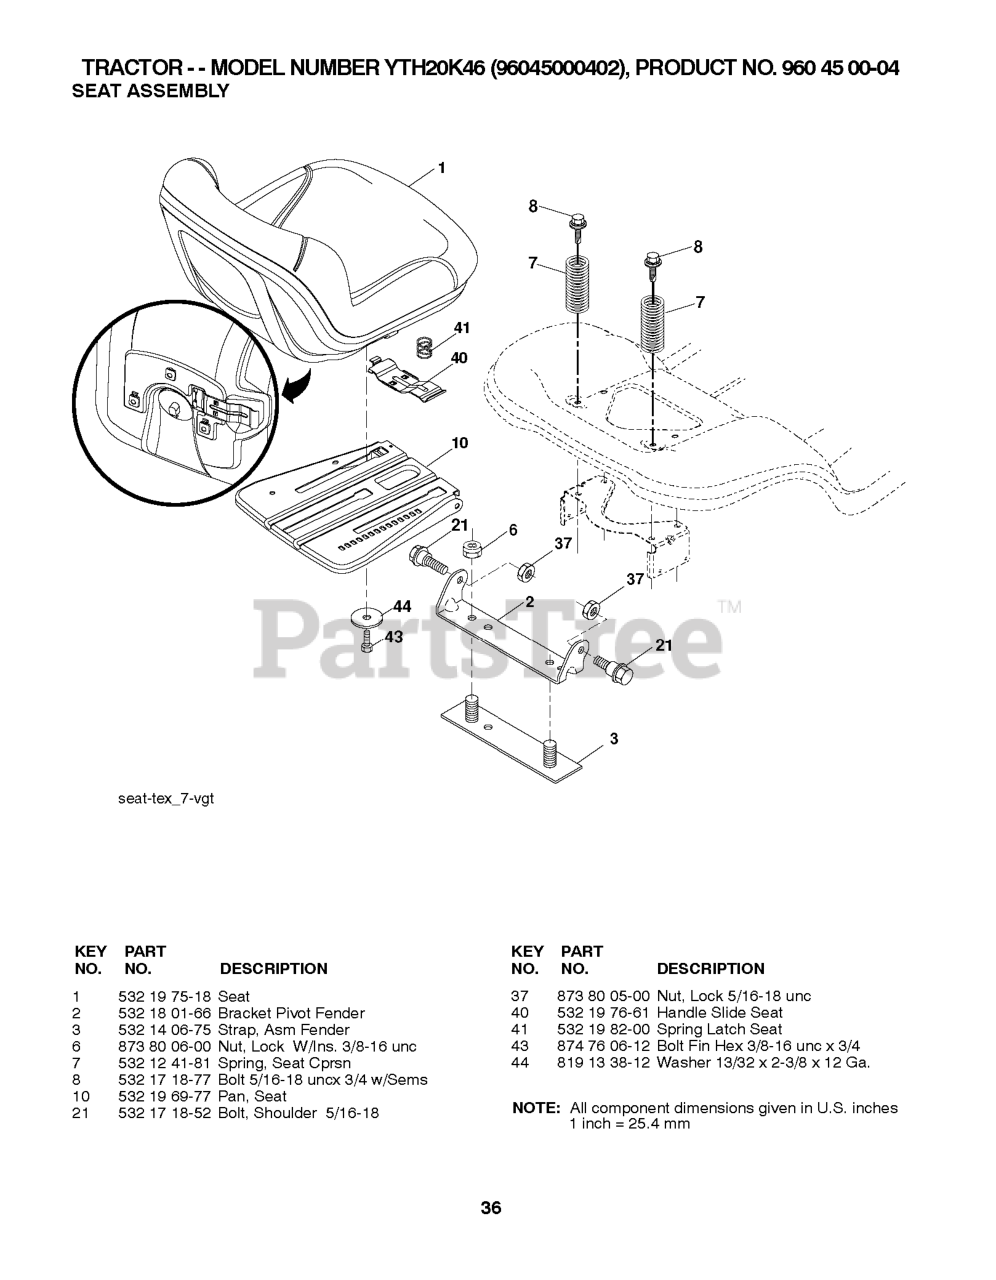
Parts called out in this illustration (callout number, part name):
1	SEAT.TH130.GRY.MILSCO.
2	BRKT.PIVOT.FENDER
3	STRAP
6	NUT
7	SPRING COMPRESSION
8	BOLT.5/16-18UNCX3/4 W/SEMS.BLK
10	PAN.ASM.SEAT.3PT
21	BOLT.SHOULDER.5/16-18
37	NUT.71038.31-18.HEX.NYLOCK
40	HANDLE.SLIDE.SEAT.TEX.BLACK
41	SPRING.LATCH.SEAT.TEX
44	WASHER 13/32 X 2-3/8 X 12GA
